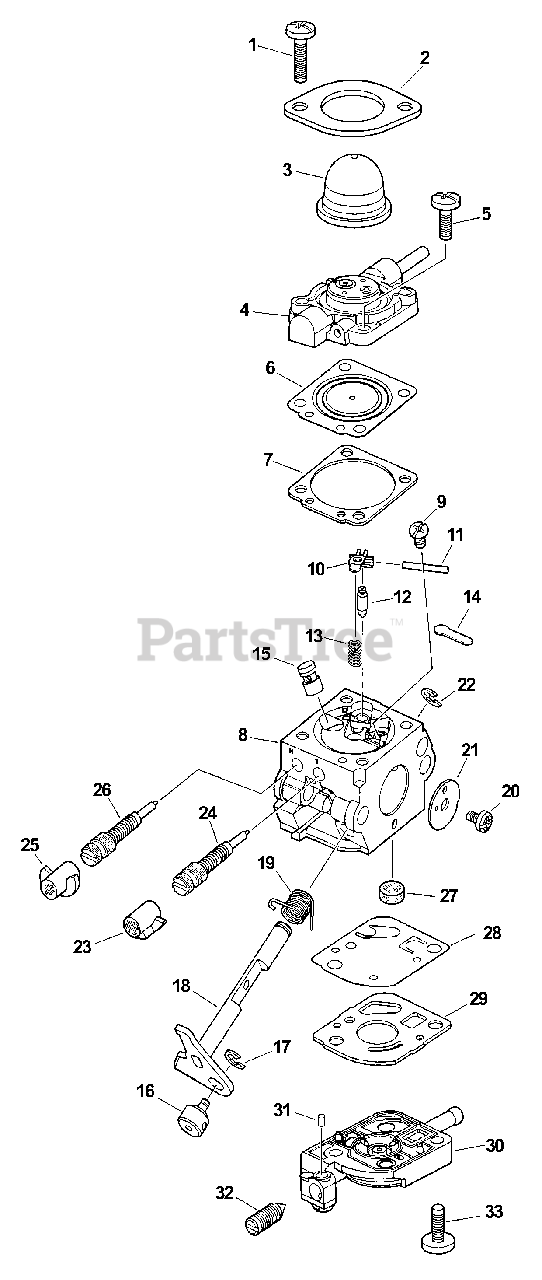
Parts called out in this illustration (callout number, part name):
2	RETAINER, PURGE BULB
3	BULB, PURGE
4	BODY ASSY, PURGE
6	DIAPHRAGM, METERING
7	GASKET, METERING
8	BODY, CARBURETOR
10	LEVER, METERING
11	PIN, METERING LEVER
12	VALVE, INLET NEEDLE
13	SPRING, METERING LEVER
14	PLUG, WELCH
15	NOZZLE, CHECK VALVE
18	SHAFT, THROTTLE
19	SPRING, THROTTLE RETURN
21	VALVE, THROTTLE
23	CAP, LIMITER - WHITE
24	NEEDLE, MIXTURE
25	CAP, LIMITER - RED
26	NEEDLE, HIGH SPEED
27	STRAINER
30	COVER, FUEL PUMP
31	PIECE, FRICTION
32	SCREW, IDLE ADJUST
